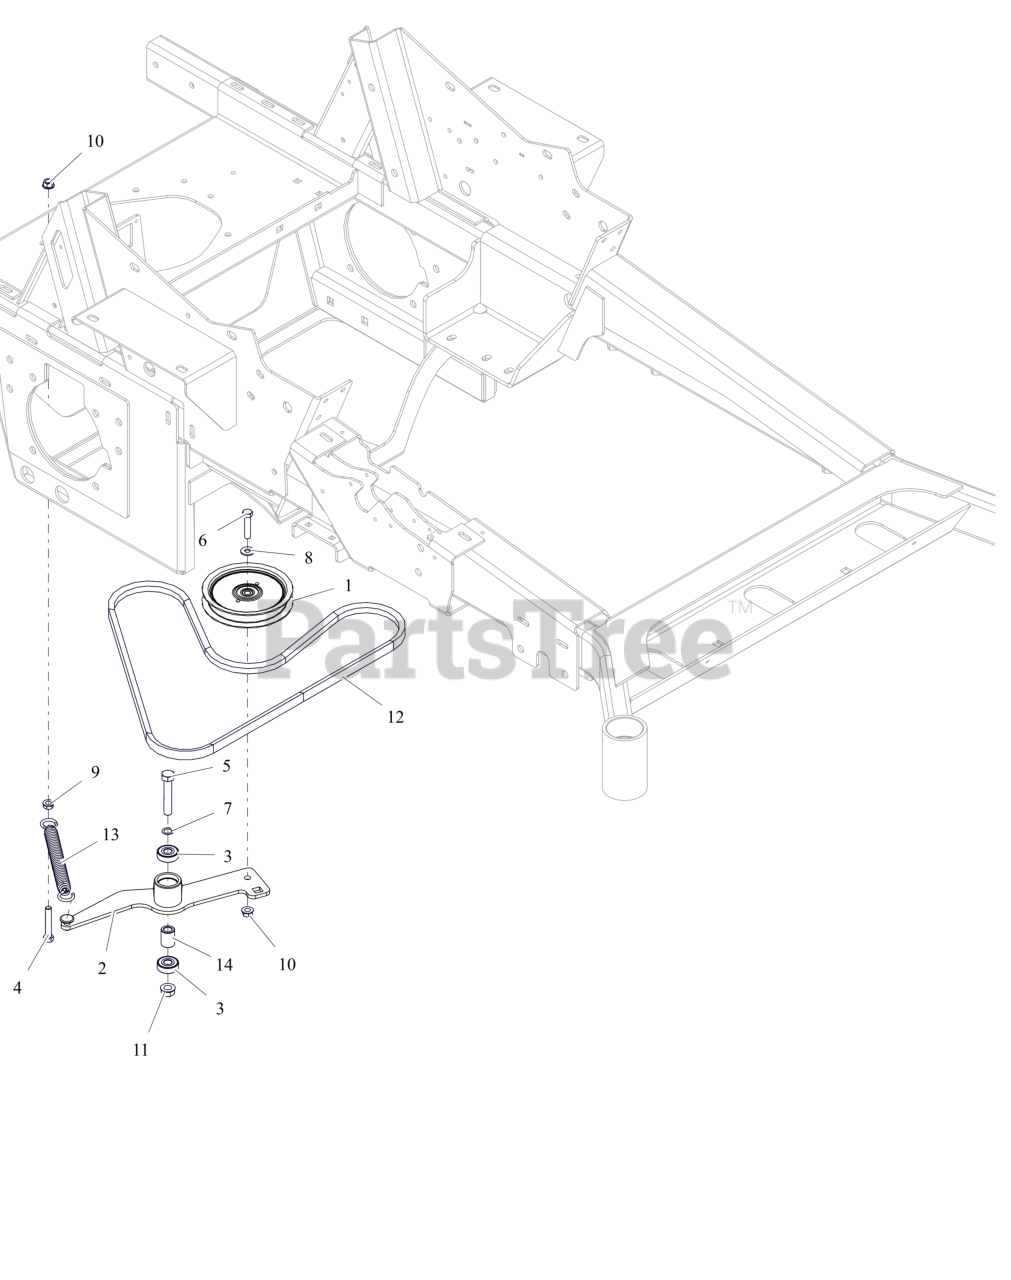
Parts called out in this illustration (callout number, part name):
1	IDLER, FLAT-5.00X.75
2	WLDMT, TRANSAXLE DRIVE IDLER ARM
3	BRG-BALL .500X1.38X.437
4	BLT,HEX .38-16X2.25 G5 ZCC
5	BLT,HEX .50-13X2.75 G5 ZCC
6	BLT, HEX .38-16X1.75 G5 ZCC
7	WASHER, .500X.750X.020 THRUST
8	WSHR,FLT .375X.875X.083 ZCC
9	NUT, SPNLK-FLG .38-16 G5 ZCC
10	NUT-LK-CTR-FLG .375-16 GF ZCC
11	NUT-LK-CTR-FLG .500-13 GG ZCC
12	V-BELT, HB RAW COGGED
13	SPRING, EXTENSION
14	SPACER .510 X .75 X 1.1485
